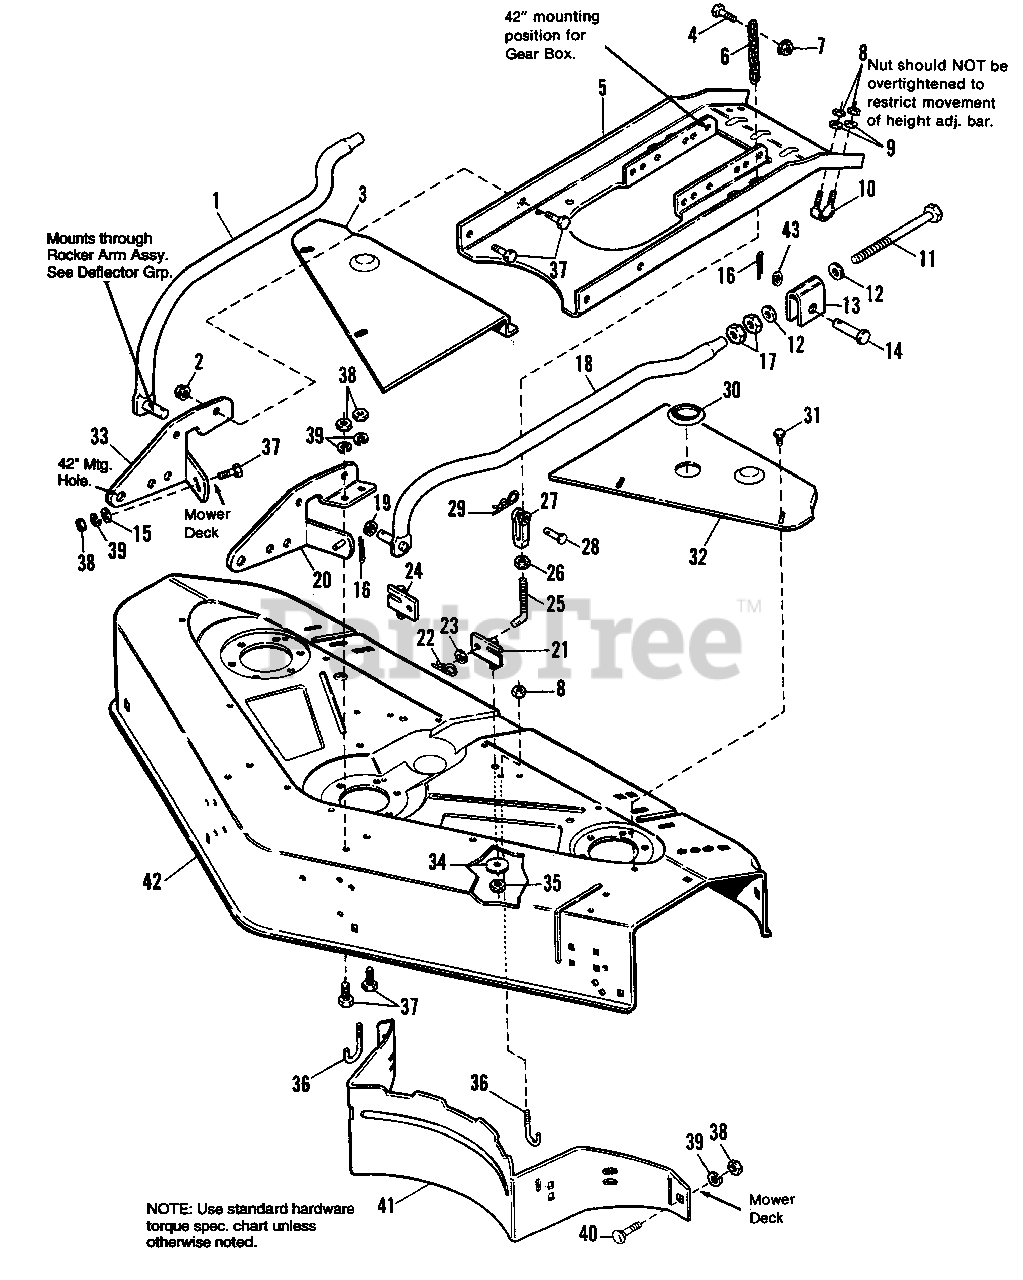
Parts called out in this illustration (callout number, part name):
1	ARM ASSY., R.H.
2	NUT, Hex Whizlock 3/8-16
3	COVER, Mower, R.H.
4	CAPSCREW, Hex Hd., 3/8-16 x 1
5	SUPPORT, "U" Channel
6	CHAIN, 5 Link (Used with 23" Tires)
6	CHAIN, 6 Link (Used with 26" Tires)
7	NUT, Hex, Flange, Lock, 3/8-16
8	NUT, Hex, Centerlock 5/16-18
9	WASHER, 5/16
11	CAPSCREW, Hex, 5/8-18 x 5-1/2
12	WASHER, 5/8
13	TRUNNION
14	PIN, Trunnion
15	WASHER, 5/16
16	PIN, Cotter, 1/8 x 1
17	NUT, Hex, Jam, 5/8-18
18	ARM ASSY., L.H.
19	WASHER, 5/8
20	BRACKET ASSY., L.H.
21	BRACKET ASSY., Lift, L.H.
22	PIN, Hair, 1/16" Wire
23	WASHER, Plain, 5/16 x 3/4 x 1/16
24	BRACKET ASSY., Lift,
25	ROD, Bolt, Lift Chain
26	NUT, Hex, Jam, 5/16-18
27	CLEVIS, Lift
28	PIN, Clevis
29	CLIP, Hair Pin
30	PLUG, Mower Cover
31	SCREW, Hex, Taptite, 1/4-20 x 3/8
32	COVER, Mower, L.H.
33	BRACKET ASSY., R.H.
34	WASHER, Plain, 13/32 x 1-1/2 x 1/8
35	NUT, Hex, Centerlock, 3/8-16
36	SCREW, Baffle Hook
37	CAPSCREW, Hex, 3/8-16 x 7/8
38	NUT, Hex, 3/8-16
39	LOCKWASHER, 3/8
40	BOLT, Carriage, 3/8-16 x 7/8
41	BAFFLE, Mower
42	HOUSING, 42" Mower
43	WASHER, 1/2"
